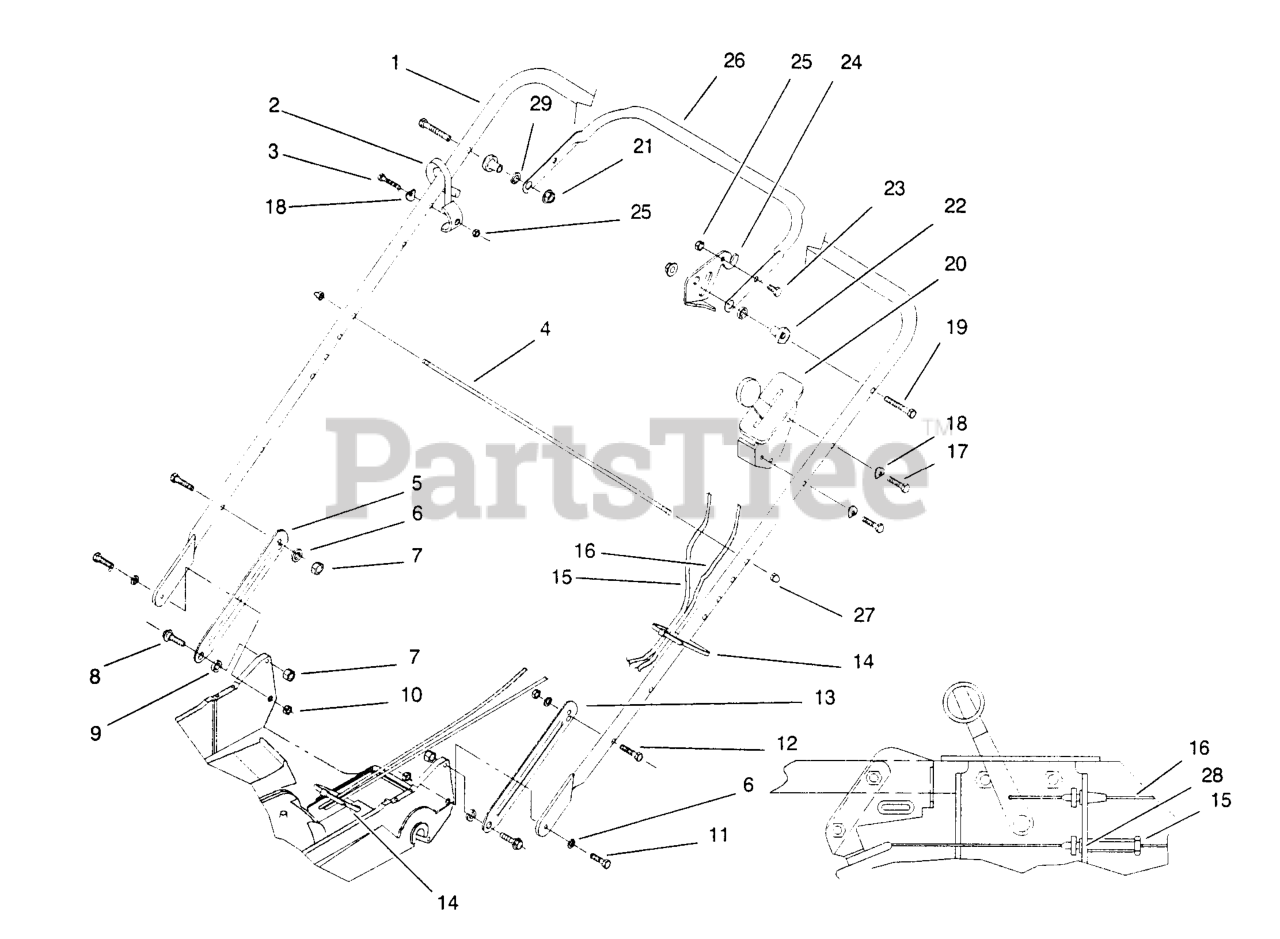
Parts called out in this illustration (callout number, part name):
2	GUIDE-ROPE
3	SCREW-HH
4	ROD-SUPPORT, BAG
6	WASHER-BELLEVILLE
7	NUT-LOCK, NI
8	SCREW-SHOULDER
9	SPACER
10	NUT-LOCK, NI
11	SCREW-HH
12	SCREW-HH
14	TIE-CABLE
15	CABLE-BRAKE
17	SCREW-HH
18	WASHER
19	SCREW-HH
20	BRACKET-CONTROL, THROTTLE
21	NUT-LOCK, NI
22	SPACER-SUPPORT
23	SCREW-HH
24	LEVER-CONTROL
25	NUT-LOCK, NI
26	BAR-CONTROL
27	NUT-CAP
29	SPACER-NYLON
